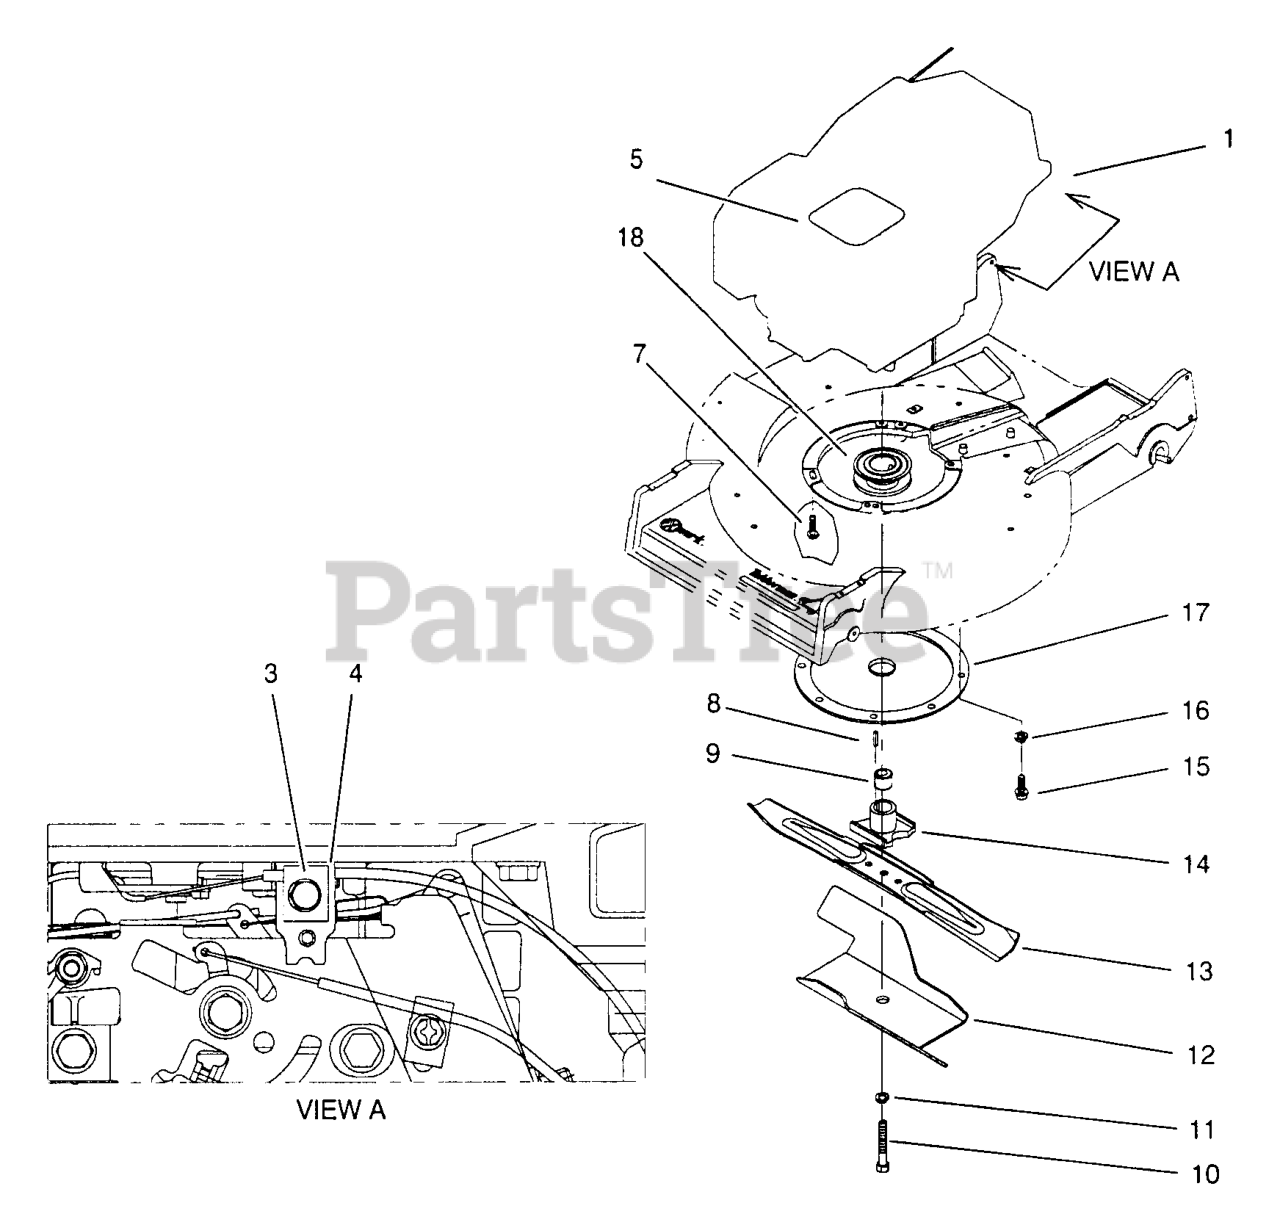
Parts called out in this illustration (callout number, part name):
3	BOLT (5X18)
7	SCREW-MOUNT, ENGINE
8	KEY-SQUARE
9	SPACER-BLADE RETAINER
10	SCREW-BLADE
11	WASHER-LOCK
12	STIFFENER-BLADE
15	Screw-HWH 5/16-18 X 3/4 Tf
16	WASHER-LOCK, INTERNAL
18	PULLEY-DRIVER
